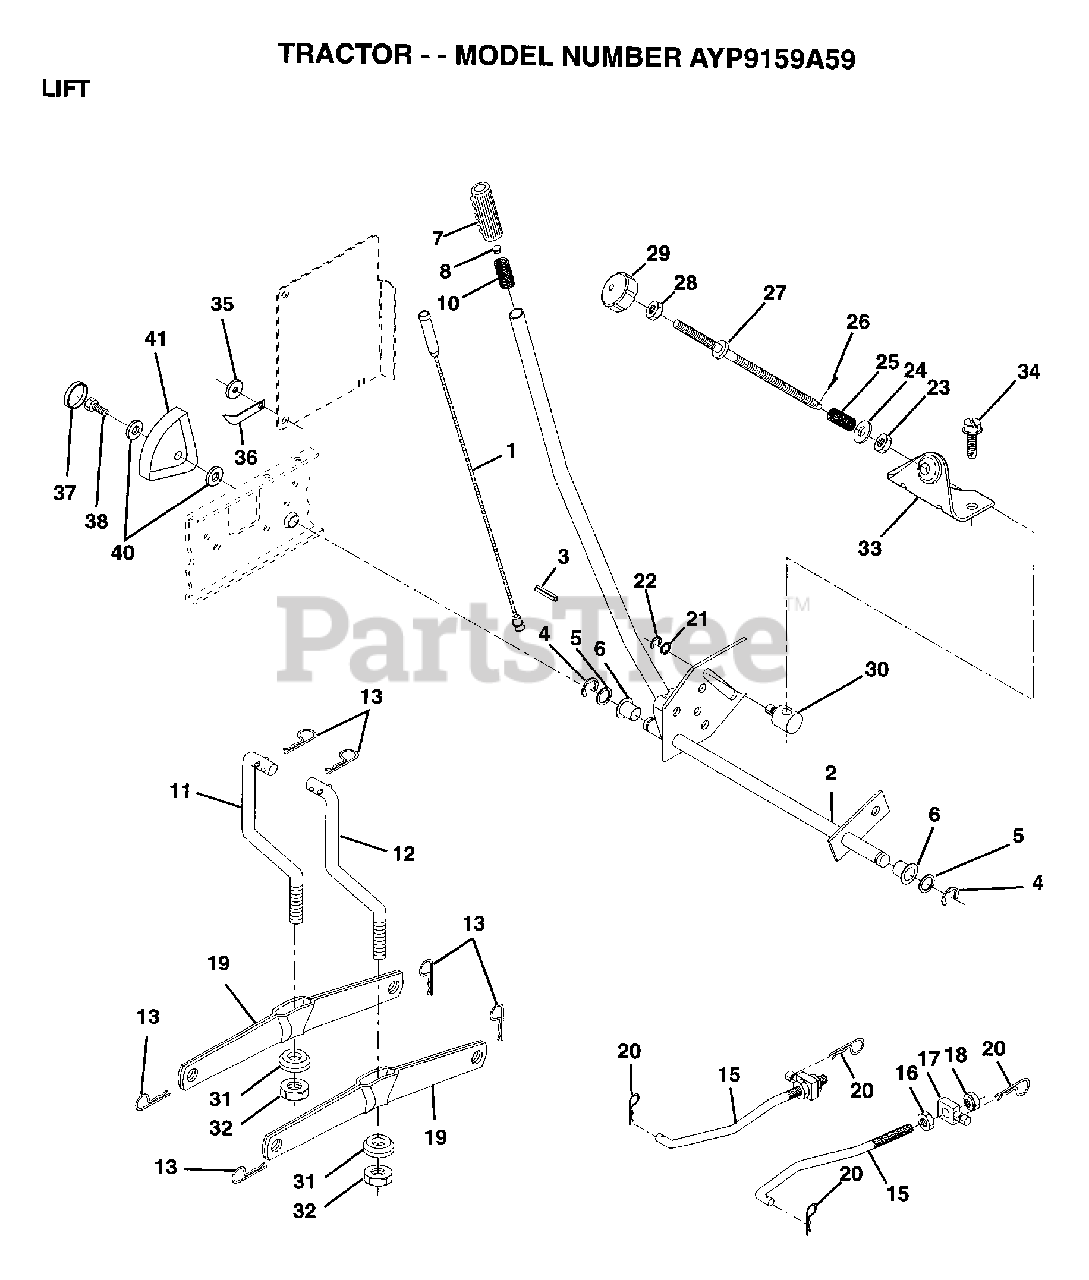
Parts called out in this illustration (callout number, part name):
1	WIRE ASM
2	HANDLE.LIFT.LH.
3	PIN GROOVE
5	WASHER
6	NYLON BEARING
7	GRIP HANDLE
15	LINK.FRONT
16	NUT
17	TRUNION
18	NUT.LK.W/WSH.1/2.
19	ARM SUSP REAR
20	RETAINER.SPRING
21	WASHER
22	KLIP RING
23	NUT T
24	WASHER
25	SPRING T
28	NUT
29	KNOB INF 3/8-16
30	TRUNION LT
31	BEARING PVT LH
32	NUT.CROWNLOCK.3/8
33	BRACKET STOP INF
34	SCREW LT
35	WASHER T
36	POINTER HGT IND
37	"PLUG,HOLE"
38	SCREW
40	WASHER
41	HEIGHT INDICATOR
